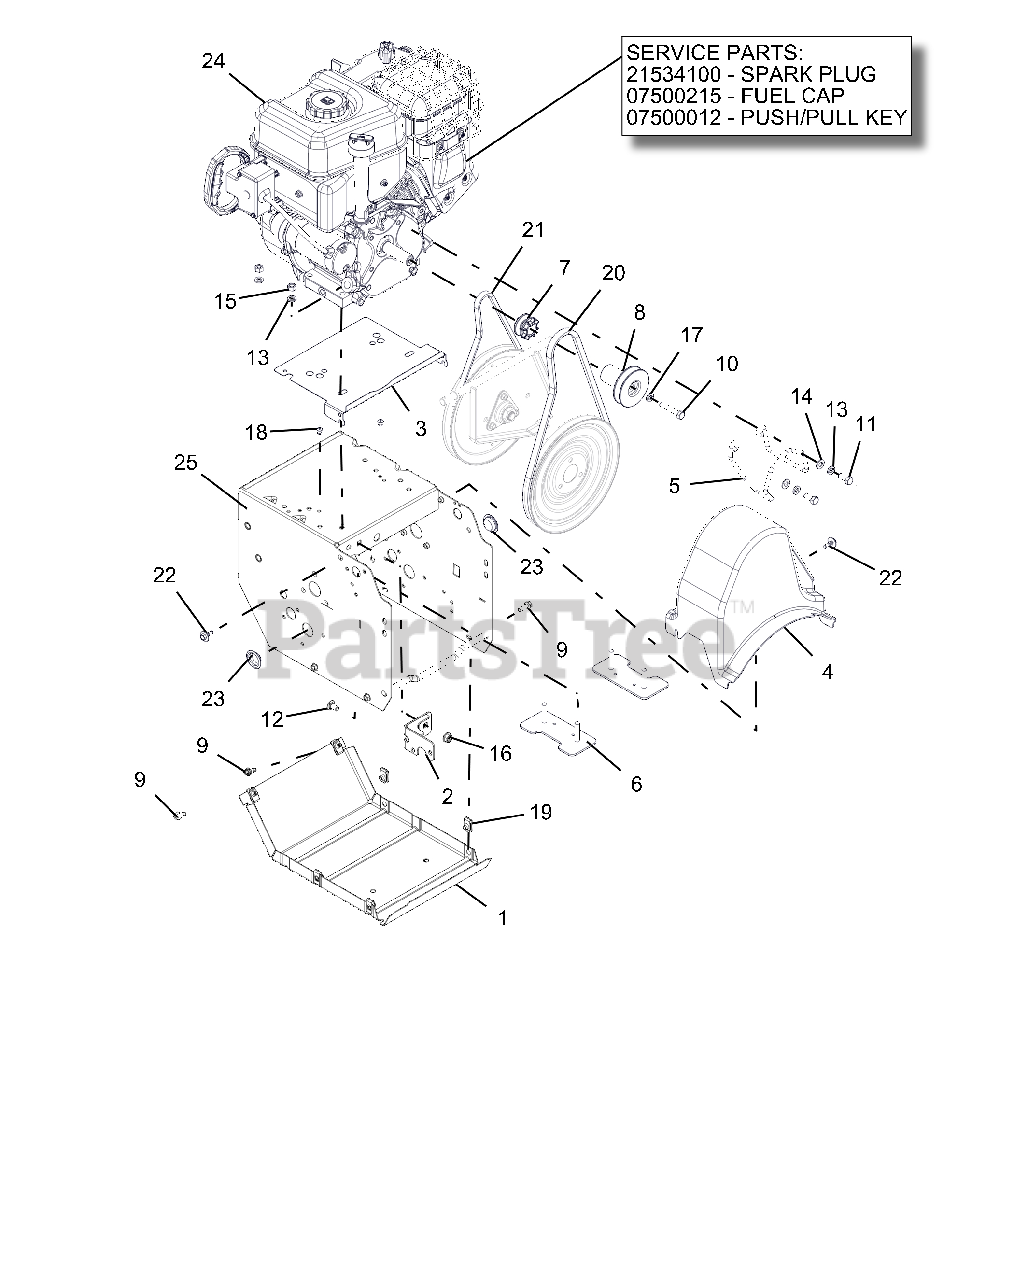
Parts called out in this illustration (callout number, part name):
1	COVER, BOTTOM
2	WELDMENT, FRAME BRACKET
3	BAFFLE,ENGINE,SMALL BLOCK
4	COVER, COMPACT BELT
5	FINGER, BELT
6	STRAP, ENGINE BOLT-WELDMENT
7	SHEAVE, TRACTION
8	SHEAVE,AUGER 3/4" PM
9	BLT-HEX .25-20X.75 HWH YZ GR5
10	@BLT-HEX .31-24X1.75 GR5 YWZC
11	BLT-HEX .31-24X.75 YWZC GR5
12	@BLT-RHDSSQNK .31-18X.62 G5YZ
13	WSHR-LK .312X.097 HVY YWZC
14	@WSHR-FL-STL.344X.688X.065YWZC
15	@NUT-HEX .31-18 YWZC
16	@NUT-LK-TOP-FLG .31-18 YWZC
17	WSHR-LK .312X.097 HVY YWZC
18	RVT-POP .187 YZ
19	NUT-RTNR .25-20X.56
20	V-BELT, HA-RAW EDGE
21	V-BELT, 3L-WRAPPED
22	SCR-TAP .25-20X.5 CAPTIVE
23	PLUG, HOLE - 1.00" FLEXTEMP
24	ENGINE, BRIGGS 900, RECOIL 60W
24	PLUG, SPARK
24	CAP, FUEL - BRIGGS & STRATTON
24	KEY, IGNITION PUSH/PULL B&S
25	WELDMENT,FRAME 920
